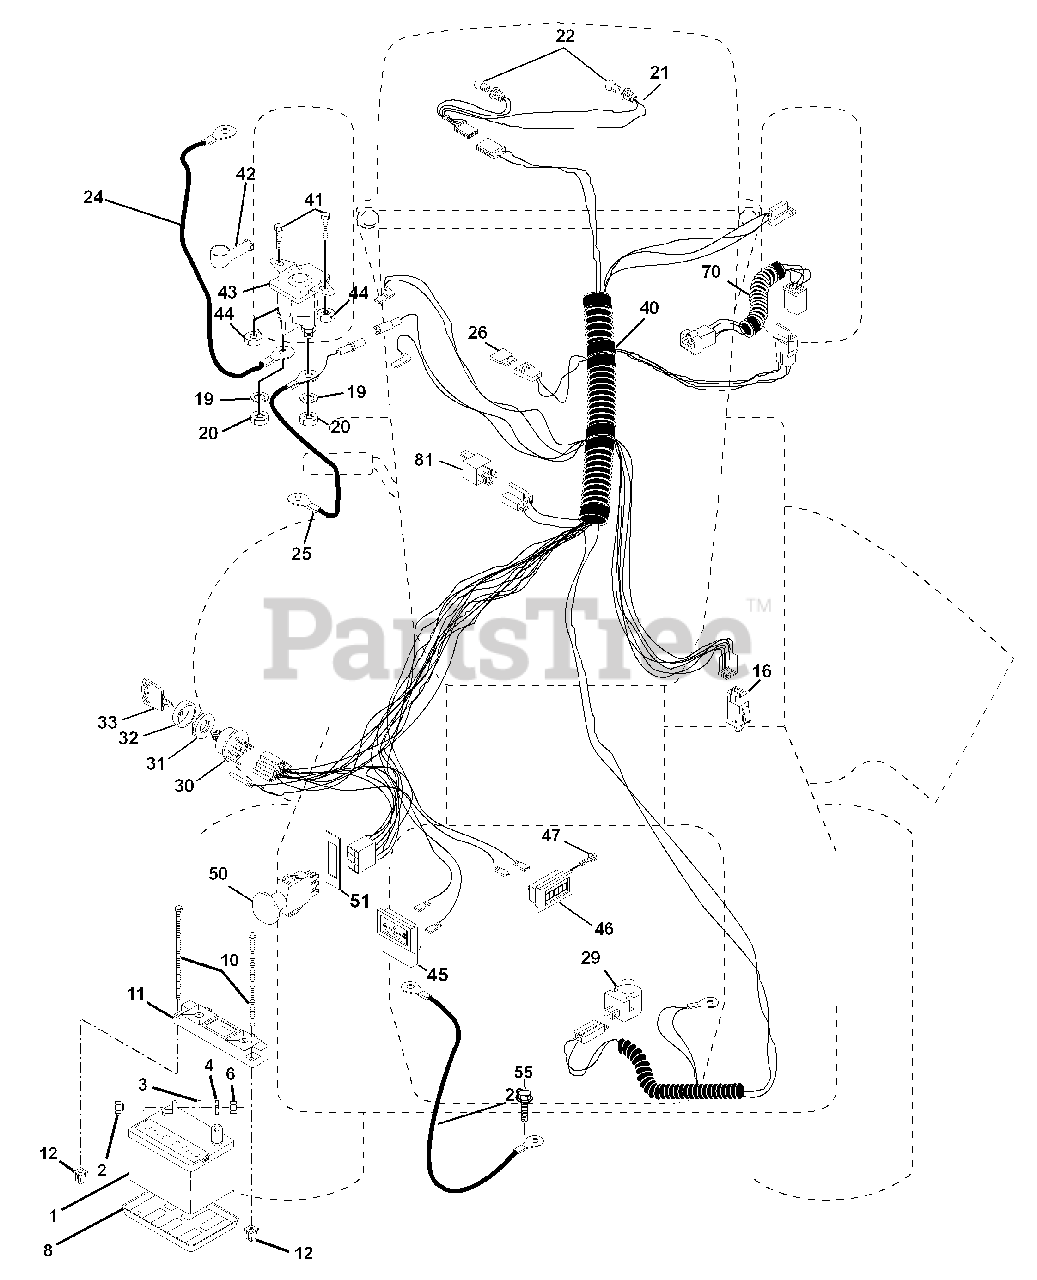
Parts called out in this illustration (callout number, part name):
1	Battery 12 Volt 35 AMP
2	Bolt Hex Hd 1/4-20unc X 3/4
3	Washer 9/32 X 5/8 X 16 Ga.
4	Washer Lock Hvy Helical 1/4
6	Nut Fin Hex 1/4-20 Unc
8	Case Battery Mech Hinge
10	Bolt Brt Frt 1/4-20 x 75 Ainc
11	Holddown Battery Front Mount
12	Nut Push Nylon 1/4" Battery Frt
16	Switch Interlock Push-In
19	Washer Lock 1/4
20	Nut Jam Hex 1/4-20 Unc
21	Harness Asm Light W/4152j
22	Bulb Light #1156
24	Cable Battery 6 Ga 11" red
25	Cable Battery 6 Ga 22" red w/16 wire
26	Fuse 30 AMP Auto Green
28	Cable Ground 6 Ga 21" black
29	Switch Plunger Nc Gray
30	Switch Ign 4 pos w/lights
31	Nut Ignition
32	Cover Sw Ignition
33	Key Ign Modelled Generic
40	Harness Ign.
41	Bolt Blk Fin Hex 1/4 - 20 x 1/2
42	Cover Terminal Red
43	Solenoid
44	Nut Keps Hex 1/4-20 Unc
45	Ammeter Rectangular 15 Amp
46	Meter Hour
47	Screw 10-24 x 1/2 Black
50	Switch PTO 3 PDT Black Delta 96
51	Ring Retainer TTO
55	Screw Thdrol 5/16-18 x 1-1/2 Tyt
70	Harness, Eng.
81	Relay Asm.
